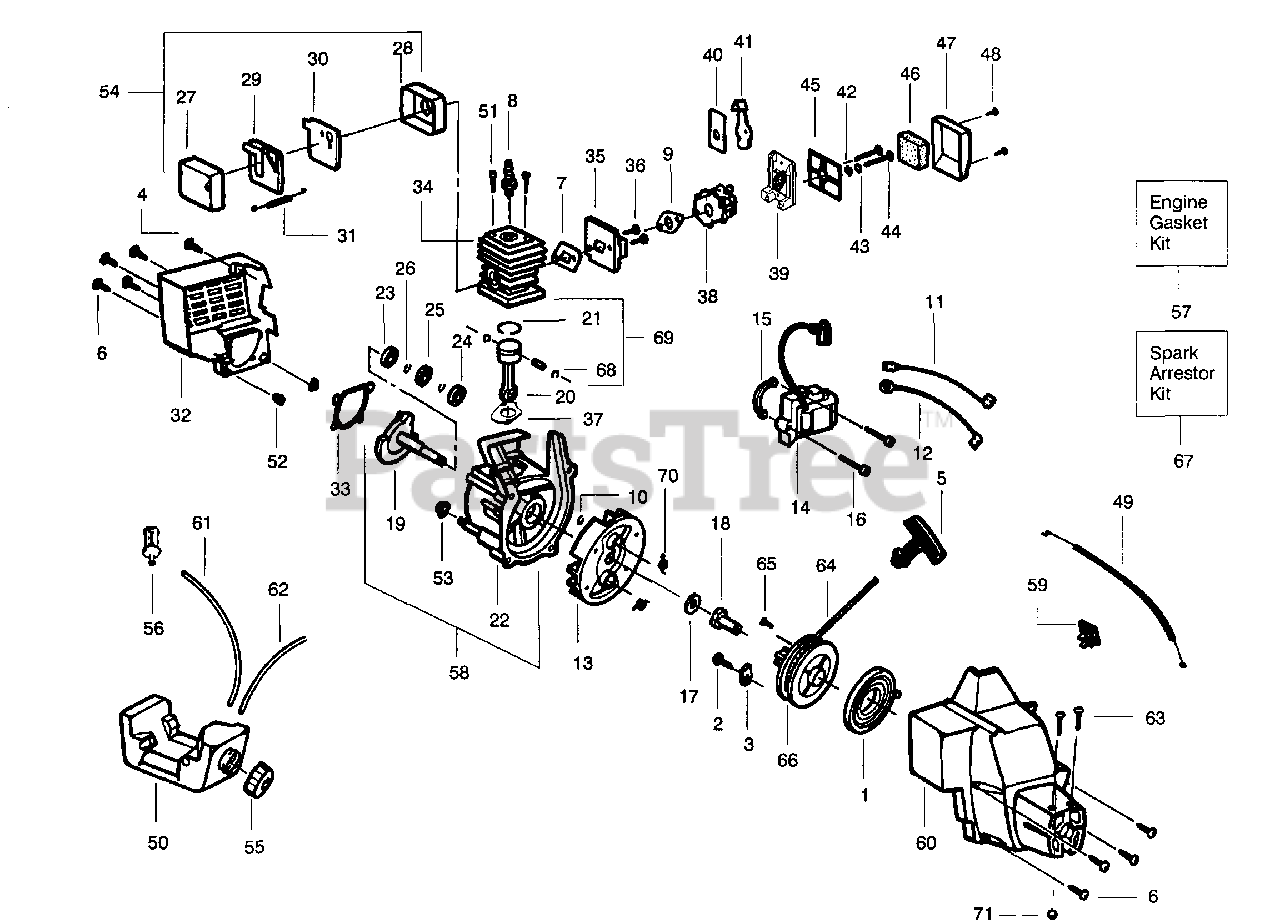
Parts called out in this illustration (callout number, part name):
1	Starter Spring
2	Screw - Pulley
3	Retainer - Pulley
4	Screw - Shrd/Fan Hsg.
5	Starter Handle
6	Screw
7	Gasket - Cylind./Carb.
8	Spark Plug (RCJ 8Y)
9	Gasket - Carb.
10	Retainer Ring - C'case
11	Lead Wire Ass'y.
12	Ground Wire Ass'y.
13	Flywheel Ass'y.
14	Ignition Module
15	Spacer - Ignit. Module
16	Screw - Ignit. Module
17	Washer - Flat
18	Drive Coupling
19	Crankshaft Ass'y.
20	Connecting Rod Ass'y.
21	Piston Ring
22	Crankcase Ass'y.
23	Inner Bearing
24	Outer Bearing
25	C'case Seal
26	Retain. Ring - C'shaft
27	Muffler Body
28	Muffler Cover
29	Muffler Baffle - Exit
30	Muffler Baffle - First
31	Muffler Spring
32	Rear Shroud
33	Gasket - C'case
34	Cylinder
35	Carb. Adapter Kit
36	Screw - Carb Adaptor
37	Gasket - Cylinder
38	Carburetor Ass'y. Kit
40	Choke Plate
41	Choke Shutter
43	Choke Spacer
45	Filter Plate
46	Air Filter Foam
47	Air Filter Cover
48	Screw - Air Box
49	Throttle Cable Ass'y.
50	Fuel Tank Ass'y
51	Screw - Cylinder
52	Isolator - Shroud
53	Isolator - Crankcase
54	Muffler Kit
55	Fuel Cap Ass'y.
56	Fuel Pickup Ass'y.
57	Engine Gasket Kit
58	C'case & C'shaft Assy.
59	On/Off Switch
60	Fan Housing Ass'y
61	Fuel Line - Carb./Purge
62	Fuel Line - Tank/Purge
64	Rope Kit
65	Screw - Rope Retain.
66	Starter Pulley Kit
67	Spark Arrestor Kit
68	Piston Pin Retainer
69	Piston Kit
70	Starter Dog Spring
